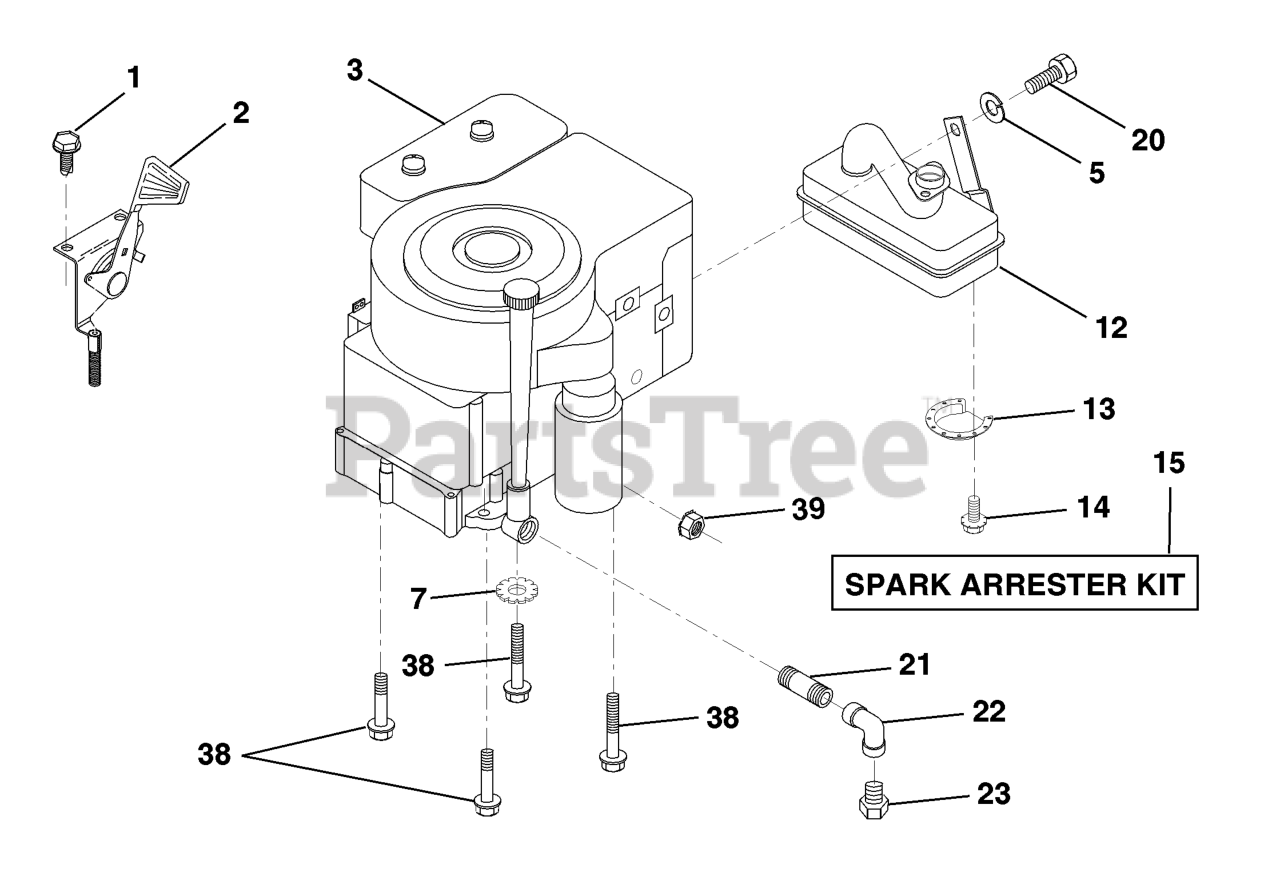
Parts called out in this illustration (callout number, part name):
2	THROTTLE CONTROL
5	WASHER.LOCK.HVY.HLCL.SPR.5/16
7	LOCKWASHER
12	MUFFLER KOH
13	DEFL MUFFLER LTV
14	SCREW
15	KIT.SPARK ARRESTOR 794945 B&S
20	Bolt, Hex Hd. 5/16-18 x 1/2
21	Nipple, Pipe 3/8 NPT x 3-1/2
22	ELBOW
23	Nipple, Pipe
38	BOLT, HEX
39	NUT
